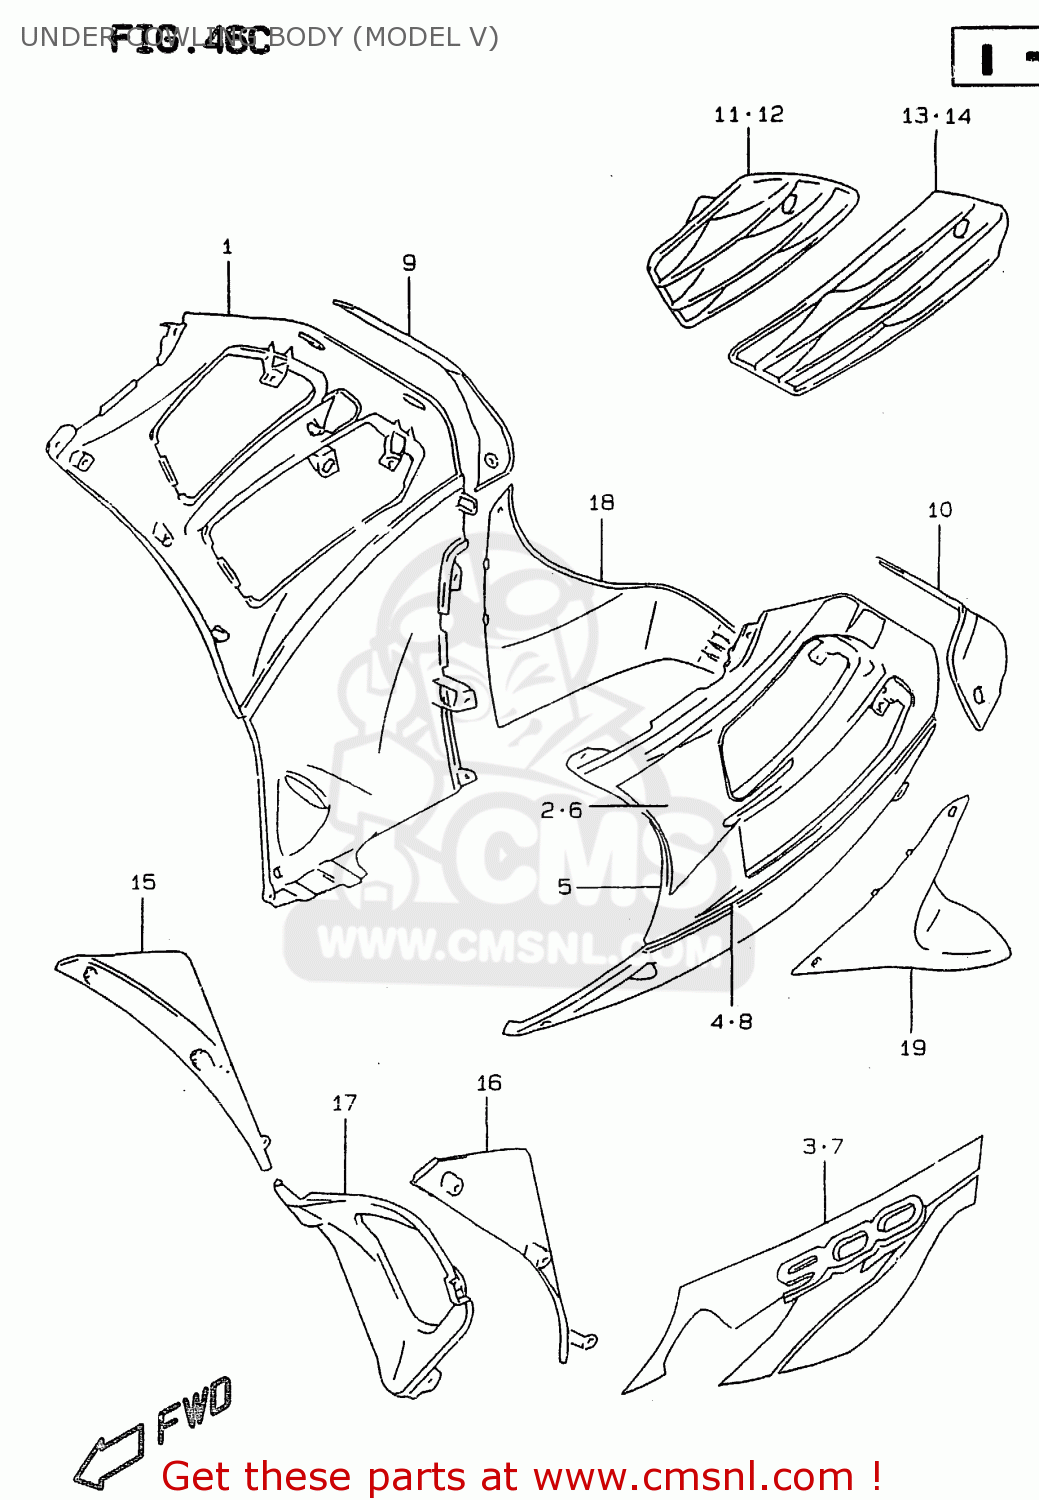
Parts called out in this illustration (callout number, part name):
1	COWLING ASSY,UNDER,R
2	TAPE SET,COWLING,UNDER
3	TAPE SET,COWLING,UNDER
4	TAPE,UNDER COWL,R
5	COWLING ASSY,UNDER,L
6	TAPE SET,COWL UNDER UPR,L
7	TAPE SET,COWL UNDER LWR,L
8	TAPE,UNDER COWL,L
9	PANEL,UNDER,R
10	PANEL,UNDER,L
11	COVER,UNDER COWL UPR,R
12	COVER,UNDER COWL UPR,L
13	COVER,UNDER COWL LWR,R
14	COVER,UNDER COWL LWR,L
15	COWLING,UNDER INNER,R
16	COWLING,UNDER INNER,L
17	COWLING,UNDER CTR
18	COWLING,UNDER RR,R
19	COWLING,UNDER RR,L
